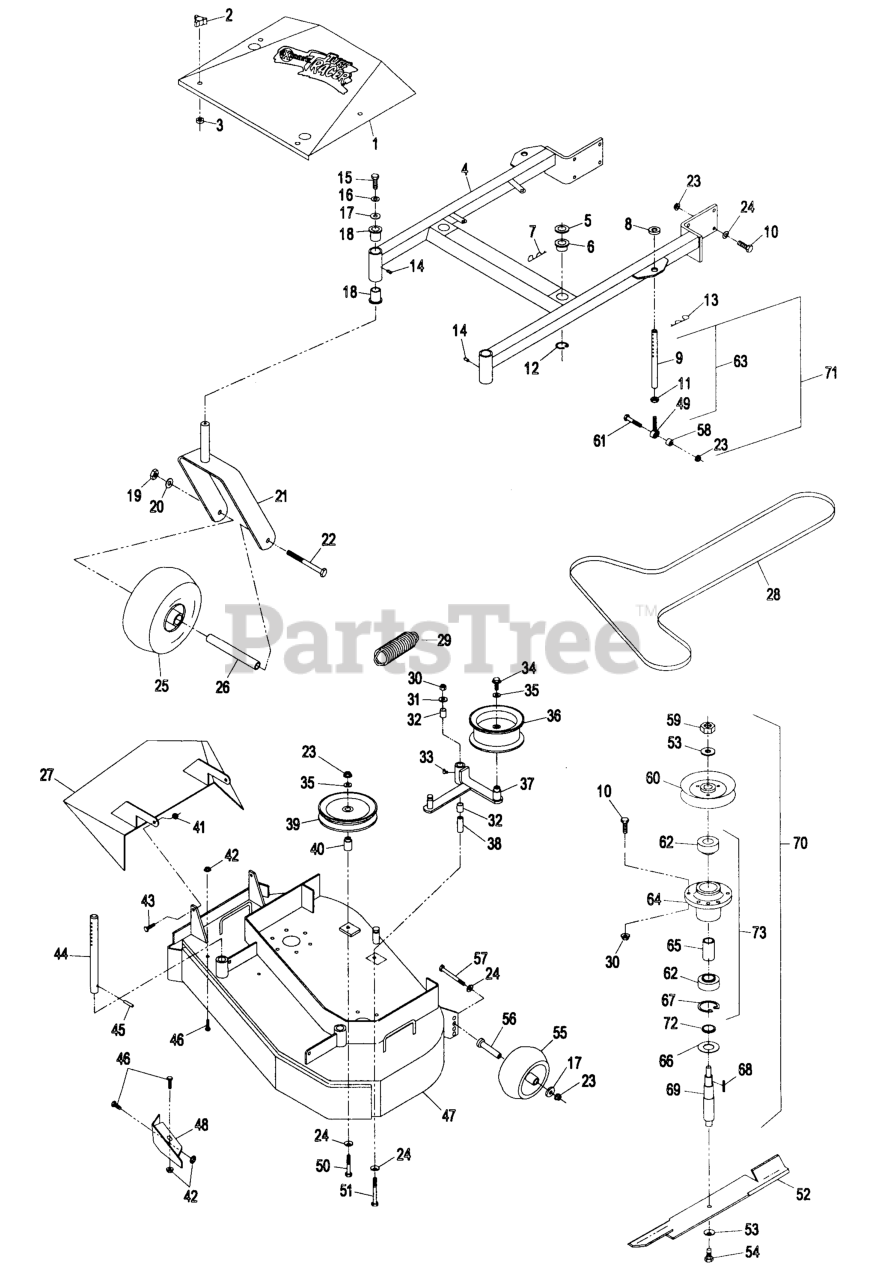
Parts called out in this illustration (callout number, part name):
1	SHIELD W/DECAL,MHP36
2	KNOB-3 PRONG
4	DECK SUPPORT W/BSHGS 36"
5	SPACER-DECK SUPPORT
6	BUSHING-DECK
9	LINK, DECK SUPPORT
13	PIN,HAIR COTTER
18	BEARING-FLANGED
28	BELT,DECK DRIVE
32	SLEEVE-BEARING
38	BUSHING-PIVOT, IDLER
39	PULLEY-IDLER
40	BUSHING-IDLER
44	ROD,DECK SUPPORT
47	ASM,DECK W/DECALS TTHP/MH
49	BALLJOINT
51	SCREW-HH
53	WASHER-SPRING
55	ROLLER-SCALP, ANTI
56	BUSHING-ROLLER
60	SHEAVE,W/HUB 5.72
62	BEARING
65	SPACER-BEARING
66	GUARD-BEARING, BOTTOM
68	KEY-RECTANGLE
69	SHAFT,SPINDLE
70	HOUSING,CUTTER COMPLETE
72	SPACER-PULLEY/BEARING
